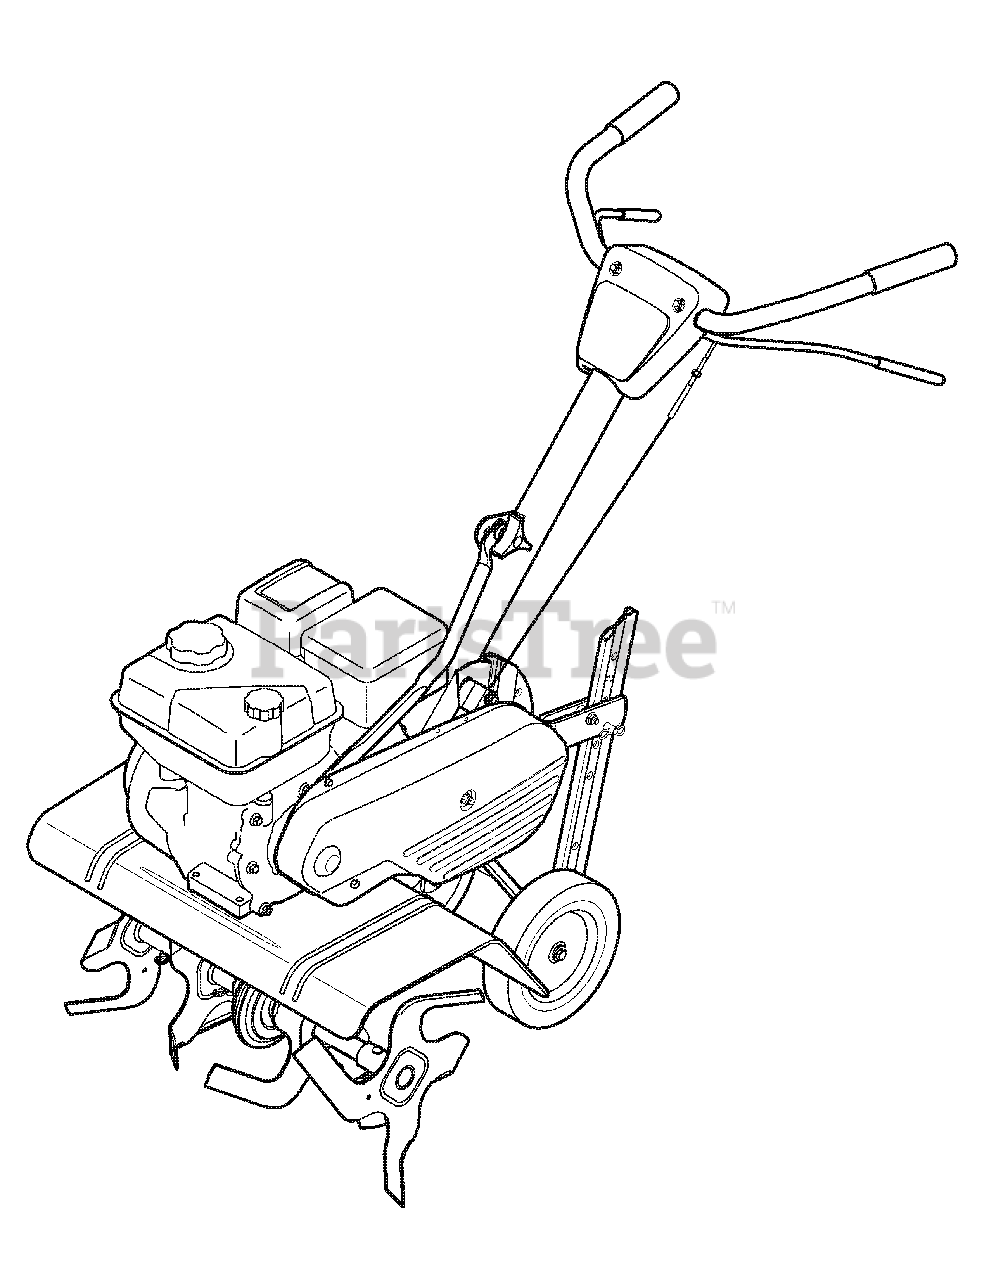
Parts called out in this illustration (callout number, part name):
NA	Pre Filter
NA	Drive Belt - REV
NA	Clutch Cable - REV
